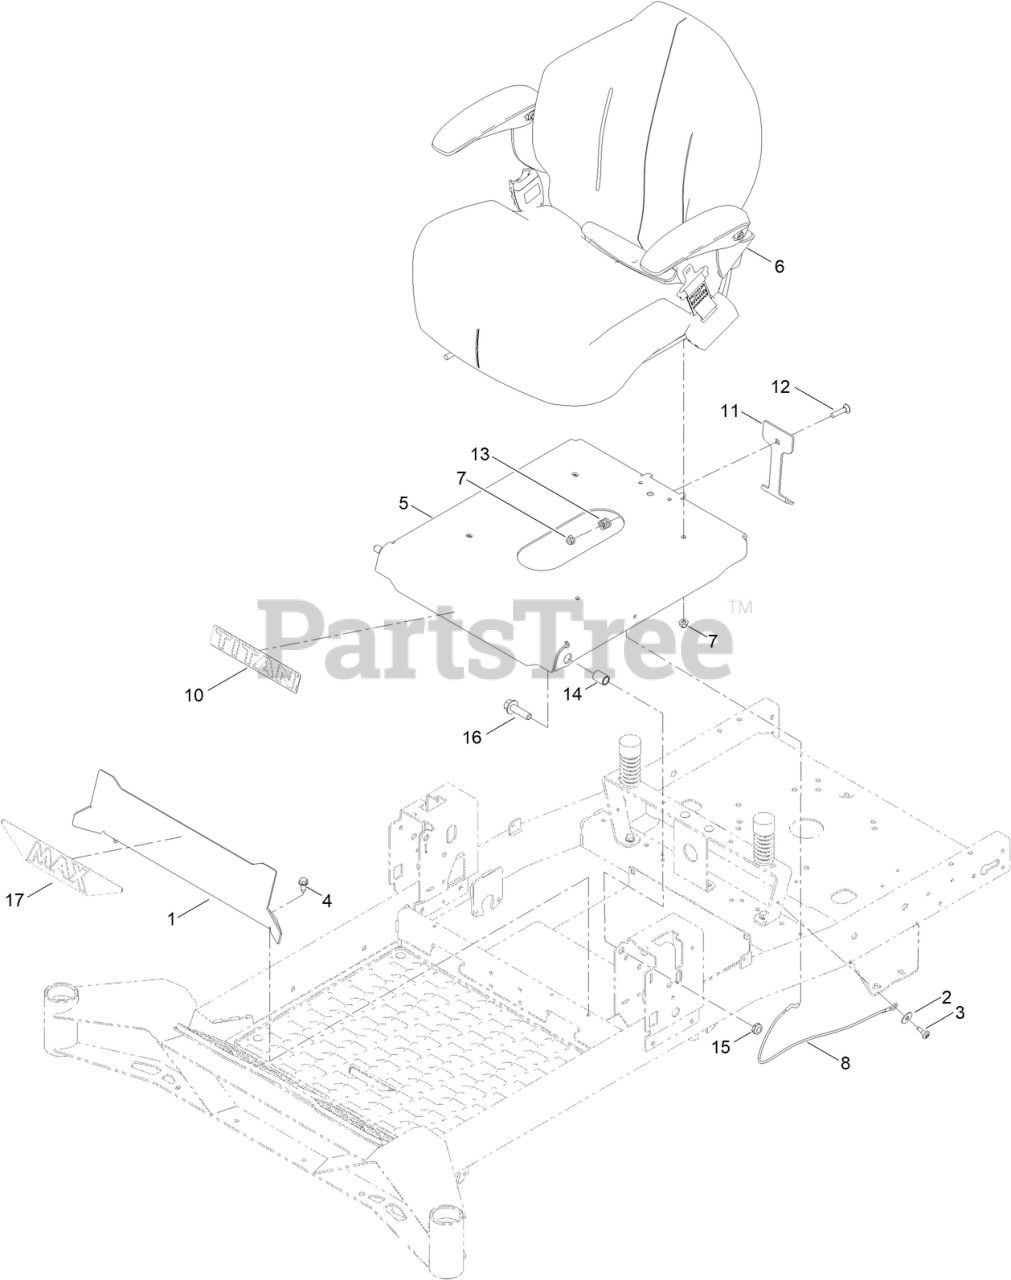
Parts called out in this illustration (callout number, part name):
1	PLATE-KICK
2	WASHER-FLAT
3	SCREW-SHOULDER
4	SCREW-HWHTF
5	PAN-SEAT
6	SEAT ASM
7	NUT-HF, NI
8	CABLE-LANYARD
10	DECAL-TITAN
11	BRACKET-LATCH, SEAT
12	BOLT-CARR
13	SPRING-COMPRESSION
14	BUSHING-PIVOT, SEAT
15	NUT-HEX
16	SCREW-HHF
17	DECAL- TC HAVOC
